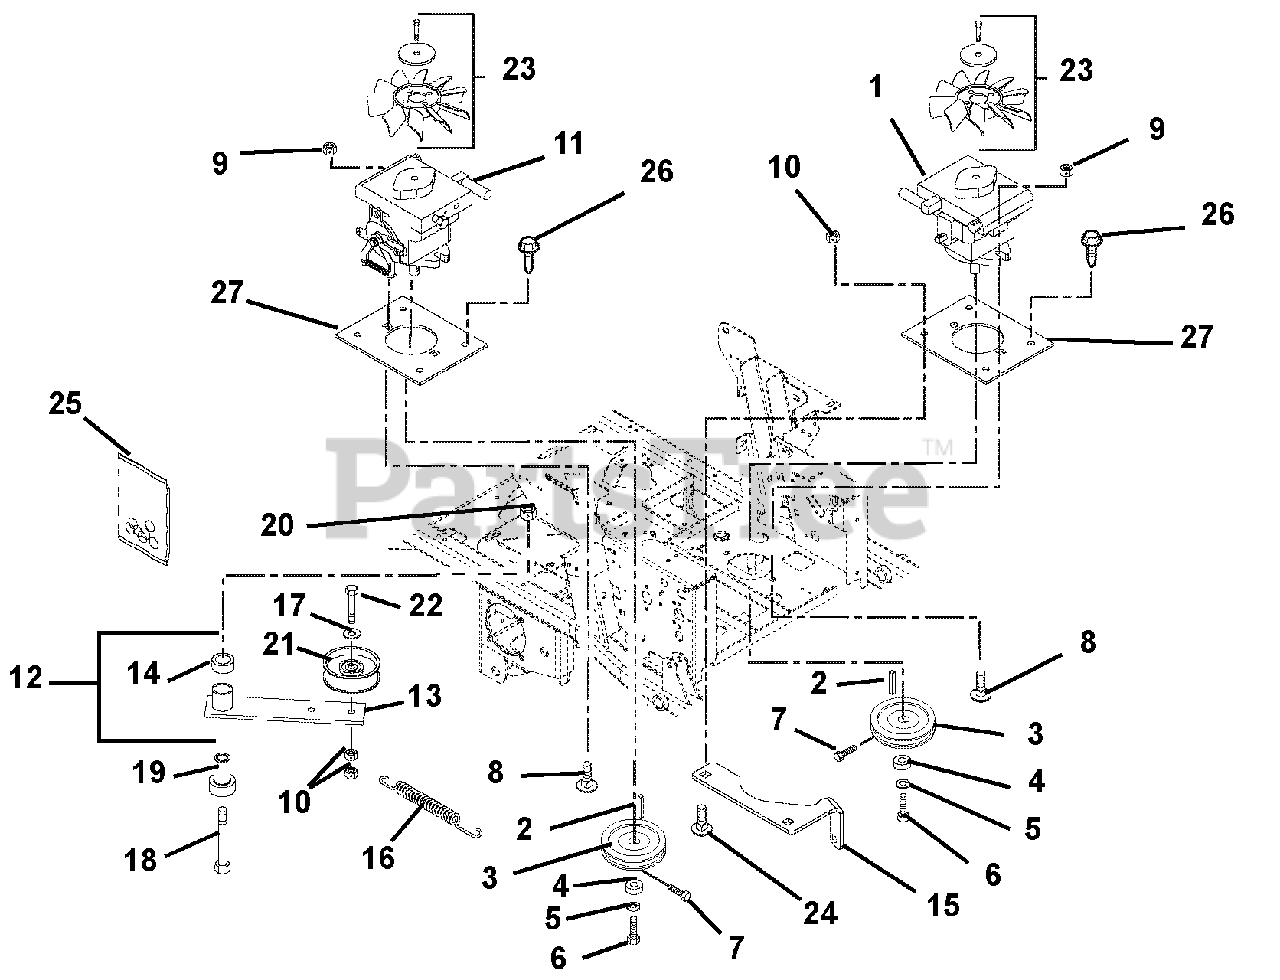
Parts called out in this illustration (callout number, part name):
1	Pump, Hydraulic
2	Key, Square 5 x 5 x 25mm Plain
3	Sheave, Poly-V .680 x 4.125 (12CC)
4	Washer, Flat Steel .281 x 1.0 x .063
5	Washer, Locking .25 x .062
6	Bolt, Hex M6 x 1.0 x 16
7	Screw, Socket Head .25-20 x .50
8	Bolt, Round Head Square Neck .44-14 x 1.50 Grade 5
9	Nut, Nyloc Flange .44-14
10	Nut-Locking-Top-Flange .38-16
11	Pump, Hydraulic PJ-Series 12CC (FAN)
12	Assembly, Idler Arm Guard Drive (Includes 13 & 14)
13	Weldment, Idler Arm Ground Drive
14	Bushing, 1.00 x 1.125 x 1.936
15	Bracket, 12CC Pump Spring Anchor
16	Spring, Tension .120 x .845 x 6.500
17	Washer, Flat Steel .39 x .75 x.125
18	Bolt, Hex .50-13 x 3.50 Grade 5
19	Bearing, Pedestal
20	Nut, Locking Top Flange .50-13
21	Assembly, 4" Idler (.75 Wide)
22	Bolt, Hex .38-16 x 2.25 Grade 5
23	Fan, Cooling
24	Bolt, Round Head Square Neck .38-16 x 1.25 Grade 5
25	Kit, Pump Seal (One kit required for each pump)
26	Screw, Tapping .38-16 x .75 Hex Washer Head Thread Rolling
27	12CC Pump Mounting Plate
